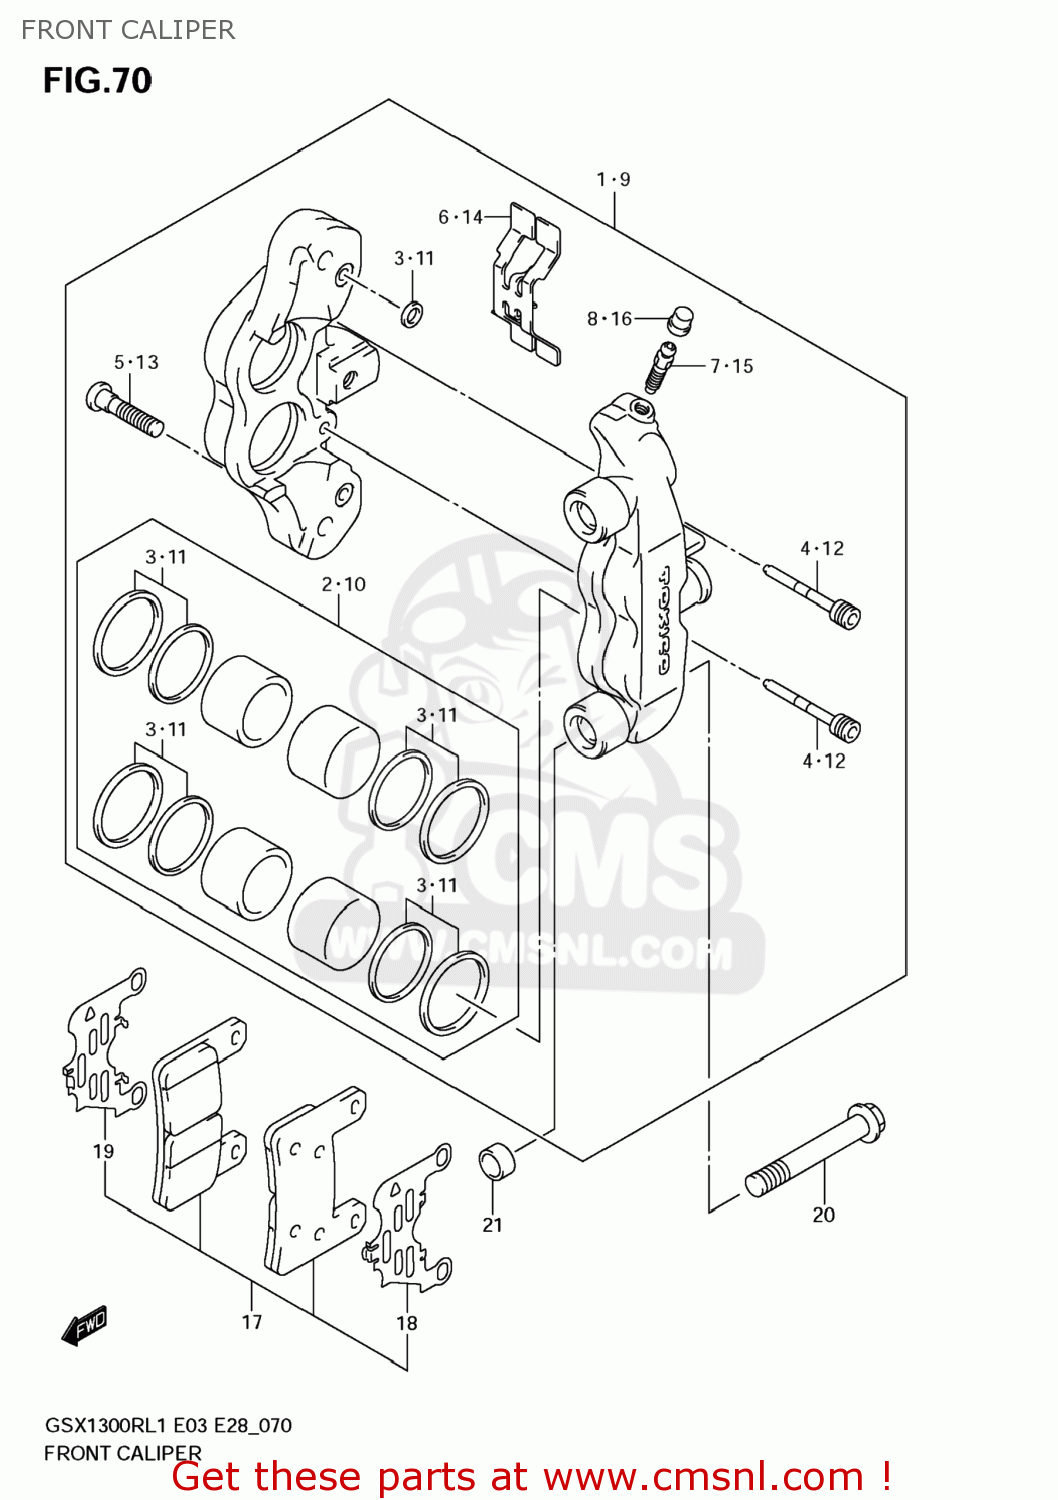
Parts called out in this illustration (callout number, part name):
1	CALIPER ASSY,FR,R
2	PISTON SET
3	SEAL SET,PISTON
4	PIN,PAD
5	BOLT
6	SPRING,PAD
7	BLEEDER
8	CAP,BLEEDER PLUG
9	CALIPER ASSY,FR,L
10	PISTON SET
11	SEAL SET,PISTON
12	PIN,PAD
13	BOLT
14	SPRING,PAD
15	BLEEDER
16	CAP,BLEEDER PLUG
17	PAD & SHIM SET (NAS)
18	SHIM,PAD A
19	SHIM,PAD B
20	BOLT(10X70)
21	PIN,CALIPER
